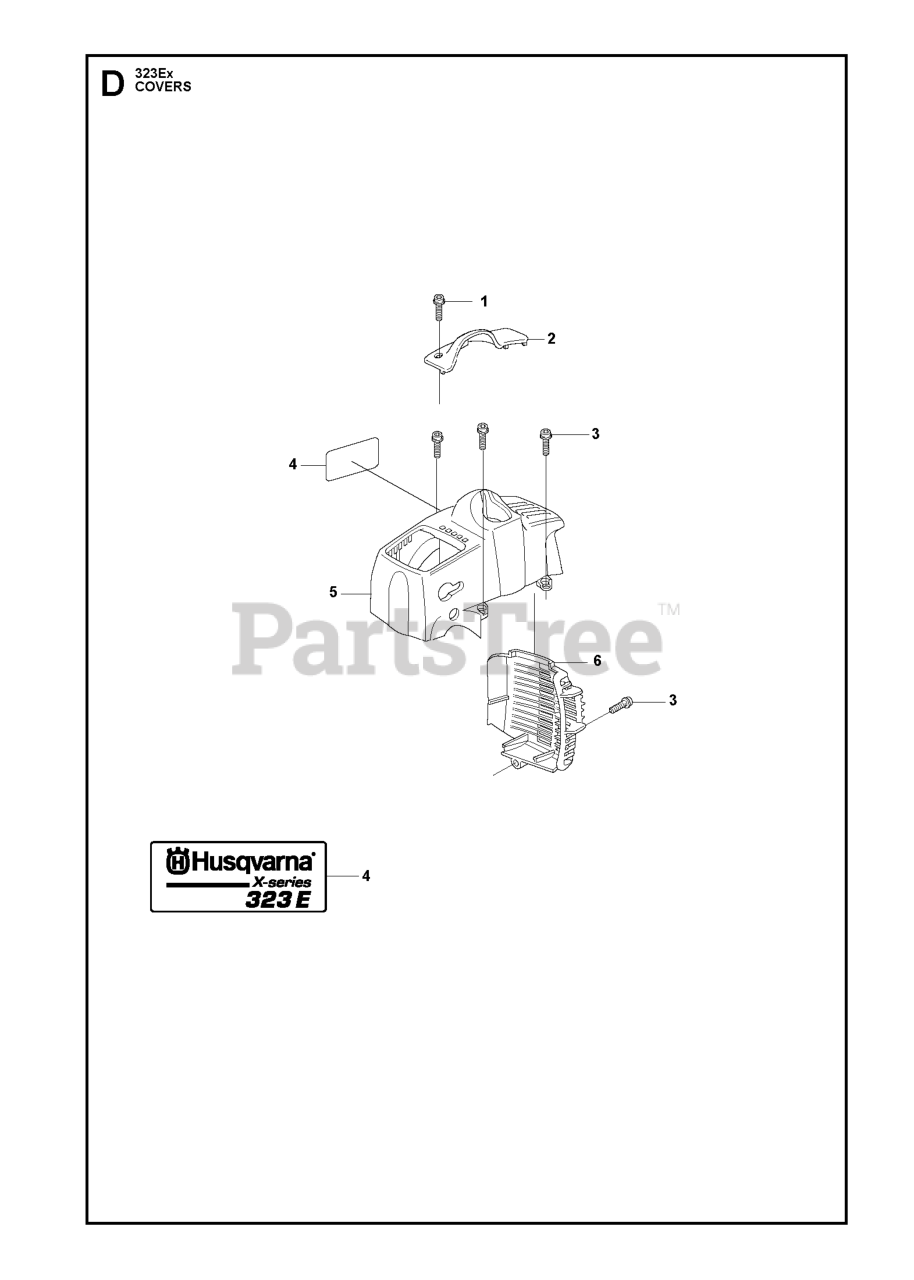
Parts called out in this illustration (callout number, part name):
3	SCREW
5	CYLINDER COVER
6	PROTECTOR
